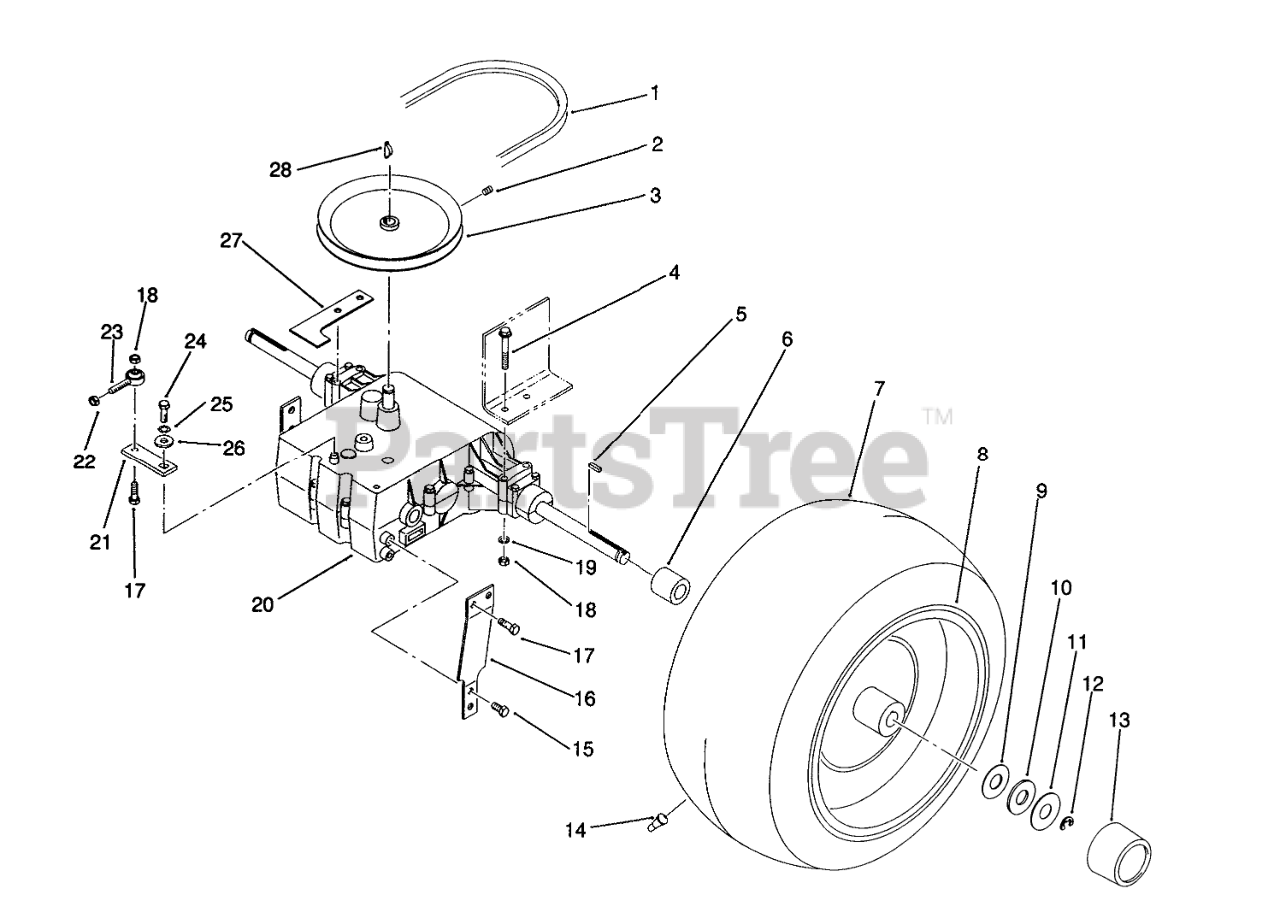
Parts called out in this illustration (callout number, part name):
1	BELT-V
2	SCREW-SQ HD SET
3	PULLEY-TRANS R
4	Screw-Hex. Washer Hd.
5	SQ KEY
6	LH AXLE SPACER
7	TIRE (20 X 10.00-10)
8	WLDMT-WHEEL & HUB
9	WASHER
10	WASHER-SHIM
11	WASHER-WHEEL
12	E Ring
13	HUB CAP-FLAT BLACK
14	VALVE
15	Screw
16	STRAP R
17	Screw-Cap Hex. Hd.
18	Nut
19	Washer
20	ASS'Y-TRANS 5-SPEED
21	ARM-TRANS. R
22	Nut
23	BALL-END
24	Screw-Hex. Hd.
25	Washer-Lock
26	WASHER
27	STOP-BRAKE R
28	KEY-HI-PRO
